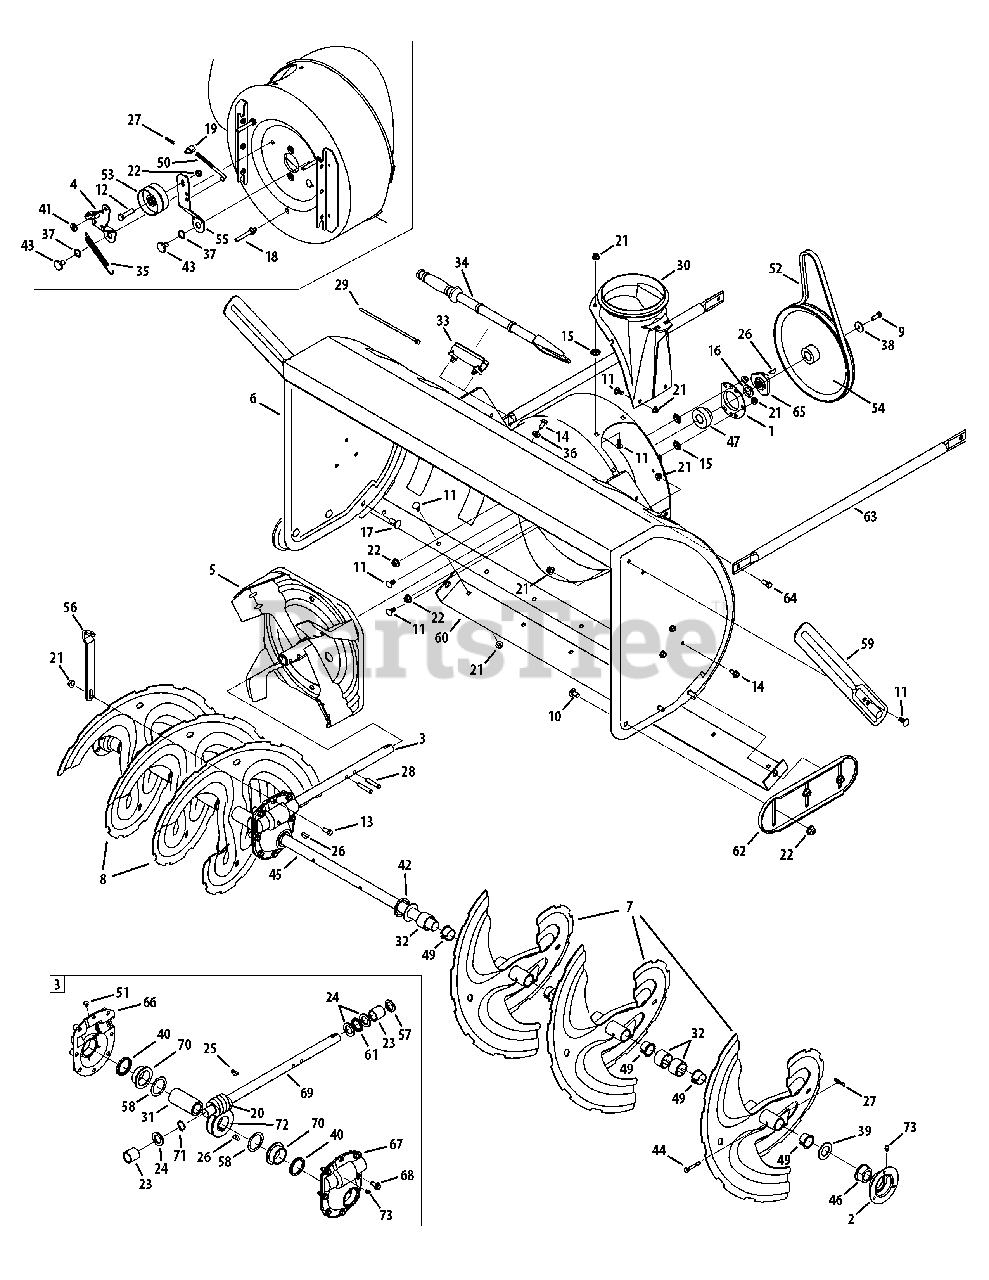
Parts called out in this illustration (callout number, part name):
1	Housing, Bearing
2	Housing, Bearing
3	Gear Box Assembly, Auger
4	Bracket Assy, Auger Brake
5	Impellar, 16"
6	Housing, Auger - 45"
7	Spiral Assy, LH
8	Spiral Assy, RH
9	Screw, 5/16-24 x .875
10	Bolt, Carriage, 3/8-16 x 1.00
11	Screw, Carriage, 5/16-18 x .75
12	Screw, Hex Cap, 3/8-16 x 1.75
13	Screw, Hex Cap, 5/16-18 x 1.00
14	Screw, 5/16-18 x .750
15	Nut, Push
16	Washer, ..76 x 1.49 x .06
17	Bolt, Carriage, 3/8-16 x 1.0
18	Screw, 5/16-18 x .4300
19	Ferrule
20	Gear, Worm, Dbl Thread
21	Nut, Flnge Lk, 5/16-18
22	Nut, Flg Lk, 3/8-16
23	Sleeve
24	Washer, Flat, .88 ID x .38 OD
25	Key, Hi Pro, 3/16 x 3/4
26	Key, Woodruff,1/4 x 3/4
27	Pin, Bowtie Cotter
28	Pin, Spirol, 5/16 x 1.75
29	Tie, Cable
30	Adapter, Chute, 6"
31	Shaft, Gear, Worm
32	Spacer, 1.0 x 1.5 x 1
33	Clip, Mounting
34	Tool, Cleanout
35	Spring, Extension
36	Washer, .349 x .879 x .063
37	Washer, .625 x .885 x .015
38	Washer, Flat, .34 x 1.50 x .150
39	Spacer, 1.004 x 1.375 x .25
40	Oil Seal
41	Washer, .344 x .75 x .12
42	Washer, 1.01 x 1.86 x .06
43	Screw, Shoulder, .625 x .17
44	Pin, Shear, .25 x 1.75
45	Axle, Spiral, 45"
46	Bearing, Flange w/Flats
47	Bearing, Self Aligning
48	Bushing, Nylon
49	Bushing, Flange, 1.051 x 1.16
50	Rod, Auger Idler
52	V Belt,4L x 44.60" Long
53	Pulley, Flat Idler, 2.75 OD
54	Pulley, Auger Drive, 10.0
55	Bracket, Auger Idler
56	Bracket, Gear Box Support
57	Seal, Oil
58	Washer, Flat, 1.52 ID x 2.0 OD
59	Drift Cutter
60	Plate, Shave, 45"
61	Bearing, Thrust
62	Shoe, Skid
63	Support Tube
64	Screw, 5/16-18 x .75
65	Pulley, Adapter, .75 Dia.
66	Hsg Assy Auger RH (Inc. 40 & 70)
67	Hsg Assy Auger LH (Inc. 40 & 70)
68	Screw, LD, 5/16-18 x .750
69	Shaft, Drive, Auger
70	Flange Bearing
71	Ext, Ret, Ring
72	Gear, Worm, LH
73	Lube Fitting, 3/16 #70
74	Bolt, Carriage, 3/8-16 x 1.25
75	Flat Washer, .385 x .870 x .092
